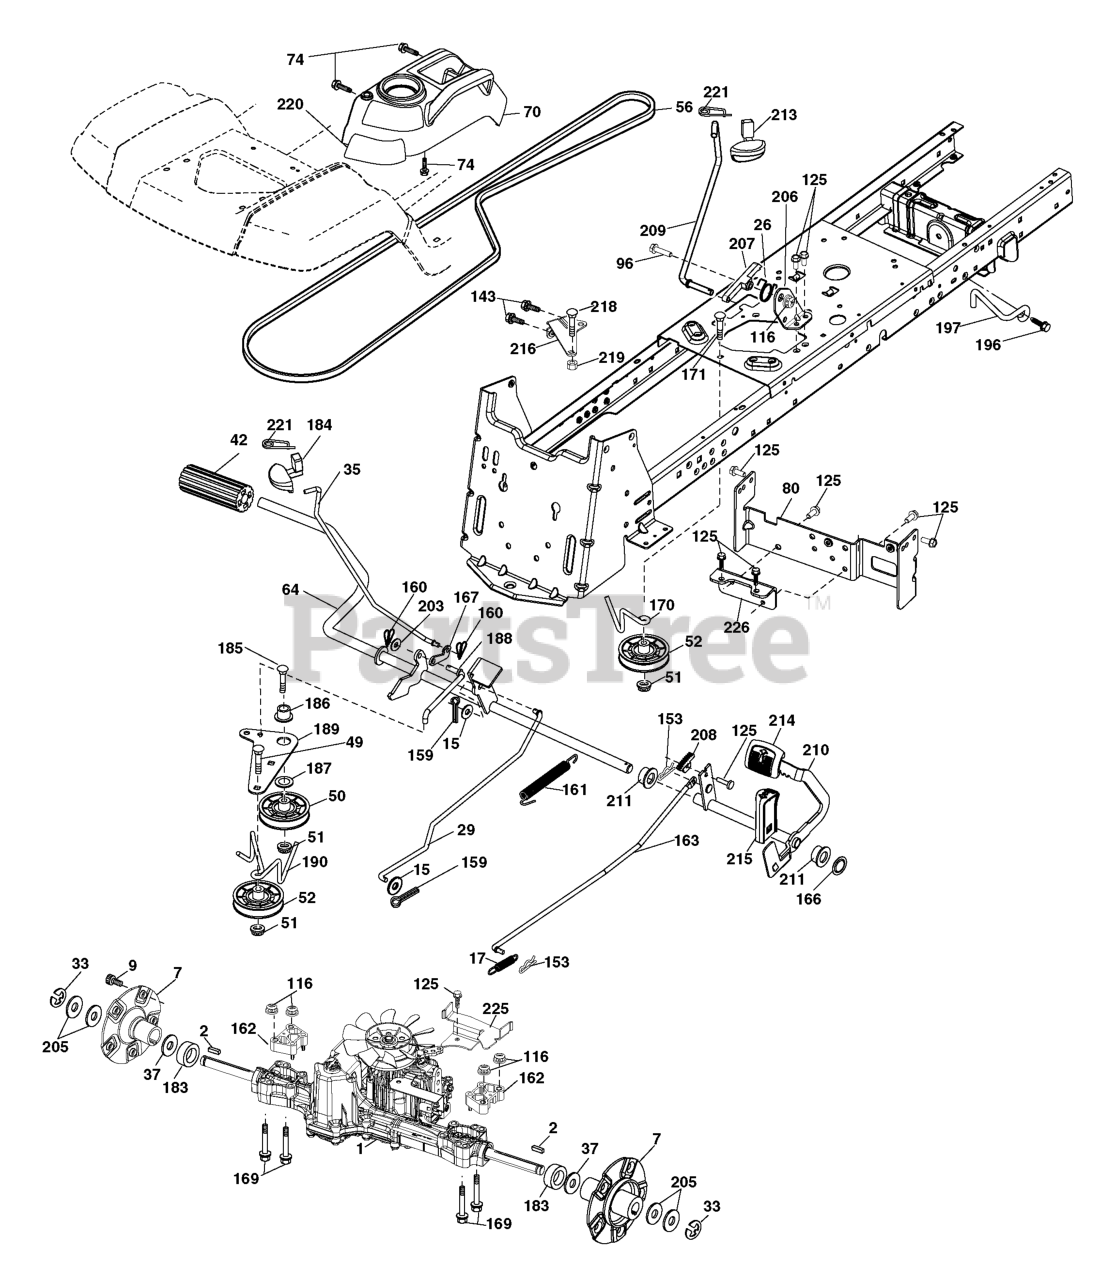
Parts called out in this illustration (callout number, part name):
2	KEY.SQUARE.187X2.500
7	HUB.ASM.WHEEL.REAR.22"
9	HUB BOLT
15	WASHER
17	SPRING.BRAKE.K46
26	SPRING.RETURN.CRUISE
29	ROD.BRAKE.K46
35	ROD.BRAKE.PARKING.GT.H
42	PEDAL COVER T
49	BOLT
50	IDLER.FLAT.910.OFFSET
51	NUT LOCK FLG 3/8-16 UNC
52	IDLER.V-GROOVE.910.OFFSET
56	V-BELT.MOWER.92.40.42/K46
64	SHAFT.ASM.PEDAL.BRK.CNTR
70	RP CONSOLE.ASM.PCH.W/TB
74	SCREW.HI-LO.CONSOLE
80	STRAP.TORQUE.HG300/3500
96	BOLT
116	NUT LOCK HEX FLANGE 5/16-18
125	SCREW
143	Screw Thdrol 5/16-18 x 1/2
153	RETAINER M
159	COTTER PIN
160	RETAINER CLIP
161	SPRING.RETURN.CLUTCH.2006
162	SPACER.TRANSAXLE.18&22
163	ROD.CONTROL.PEDAL.K46
166	NUT.PUSH.625.2006
167	LATCH.BRAKE.SPRING
169	BOLT.HEX.FLNG.5/16-18X3.75
170	KEEPER.V-IDLER.CENTER.
171	BOLT
183	SPACER.SPLIT.800X.350
184	HANDLE.PARKG.BRK.HUSQ X667
185	BOLT
186	SPACER.RETAINER
187	WASHER 12/32X2X10GA
188	RP.LINK.CLUTCH.GROUND.DRIVE
189	BELLCRANK.GROUND.DRIVE.TEX.
190	KEEPER.BELLCRANK.DRIVE
196	SCREW 3/8-16X1
197	BRKT.ANIT-ROTATION.CLUTCH
203	WASHER
206	BRKT.MOUNT.LATCH.CRUIS
207	LATCH.CONTROL.CRUISE
208	GEAR.SECTOR.CONTROL.CR
209	ROD.CONTROL.CRUISE.GT.
210	ROCKER.ASM.PEDAL.CONTR
211	BEARING.NYLON
213	KNOB.CONTROL.CRUSIE.HU
214	PEDAL.FORWARD.TEX.GT.4
215	PEDAL.REVERSE.TEX.GT.4
216	BRACKET.PULLEY.IDLER.W/TEX
218	BOLT.5/16-18X1-1/4 FULL.THREAD
219	SPACER.FENDER
220	REFLECTOR.RH.TEX GT
221	RETAINER.SPRING.CLIP.H
222	WASHER
225	KEEPER.BELT.TRANSAXLE.K46
226	BRKT.MOUNT.TORQUE.K46.
